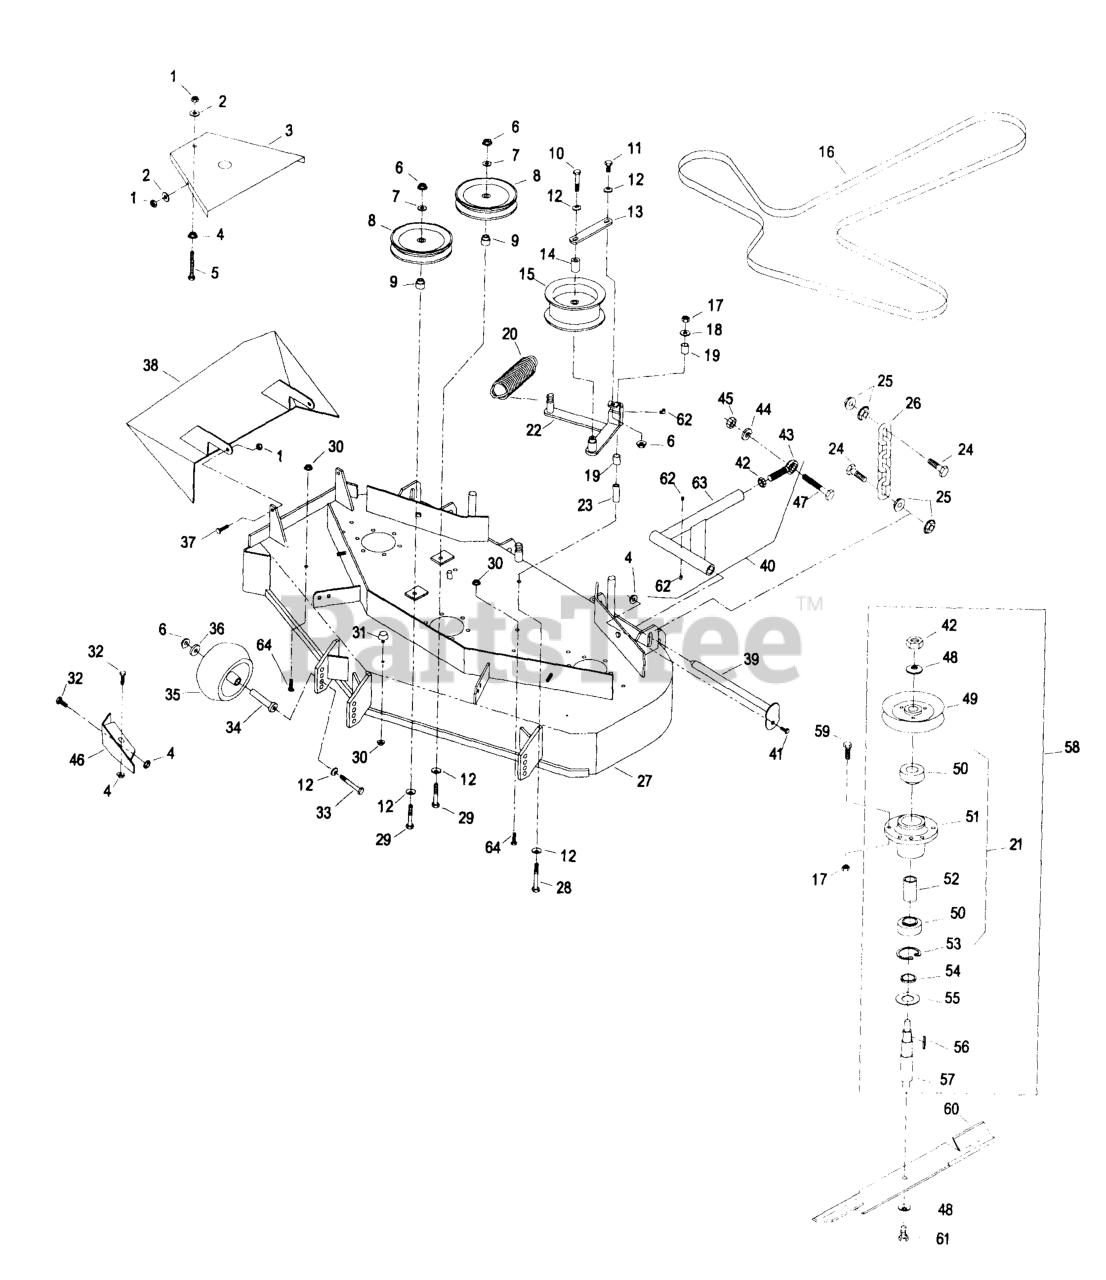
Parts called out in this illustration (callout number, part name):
5	BOLT,TAP HH
8	PULLEY-IDLER
9	BUSHING-IDLER
16	BELT,DECK DRIVE
19	SLEEVE-BEARING
23	BUSHING-PIVOT, IDLER
24	SCREW-CAP, HH
26	CHAIN-LIFT, DECK
27	ASM,DECK W/DECALS LHP48(S
28	SCREW-HH
34	BUSHING-ROLLER
35	ROLLER-SCALP, ANTI
39	PIN-STRUT
43	BALLJOINT-SPHERICAL
48	WASHER-SPRING
49	SHEAVE,W/HUB 5.72
50	BEARING
52	SPACER-BEARING
54	SPACER-PULLEY/BEARING
55	GUARD-BEARING, BOTTOM
56	KEY-RECTANGLE
57	SHAFT,SPINDLE
58	HOUSING,CUTTER COMPLETE
